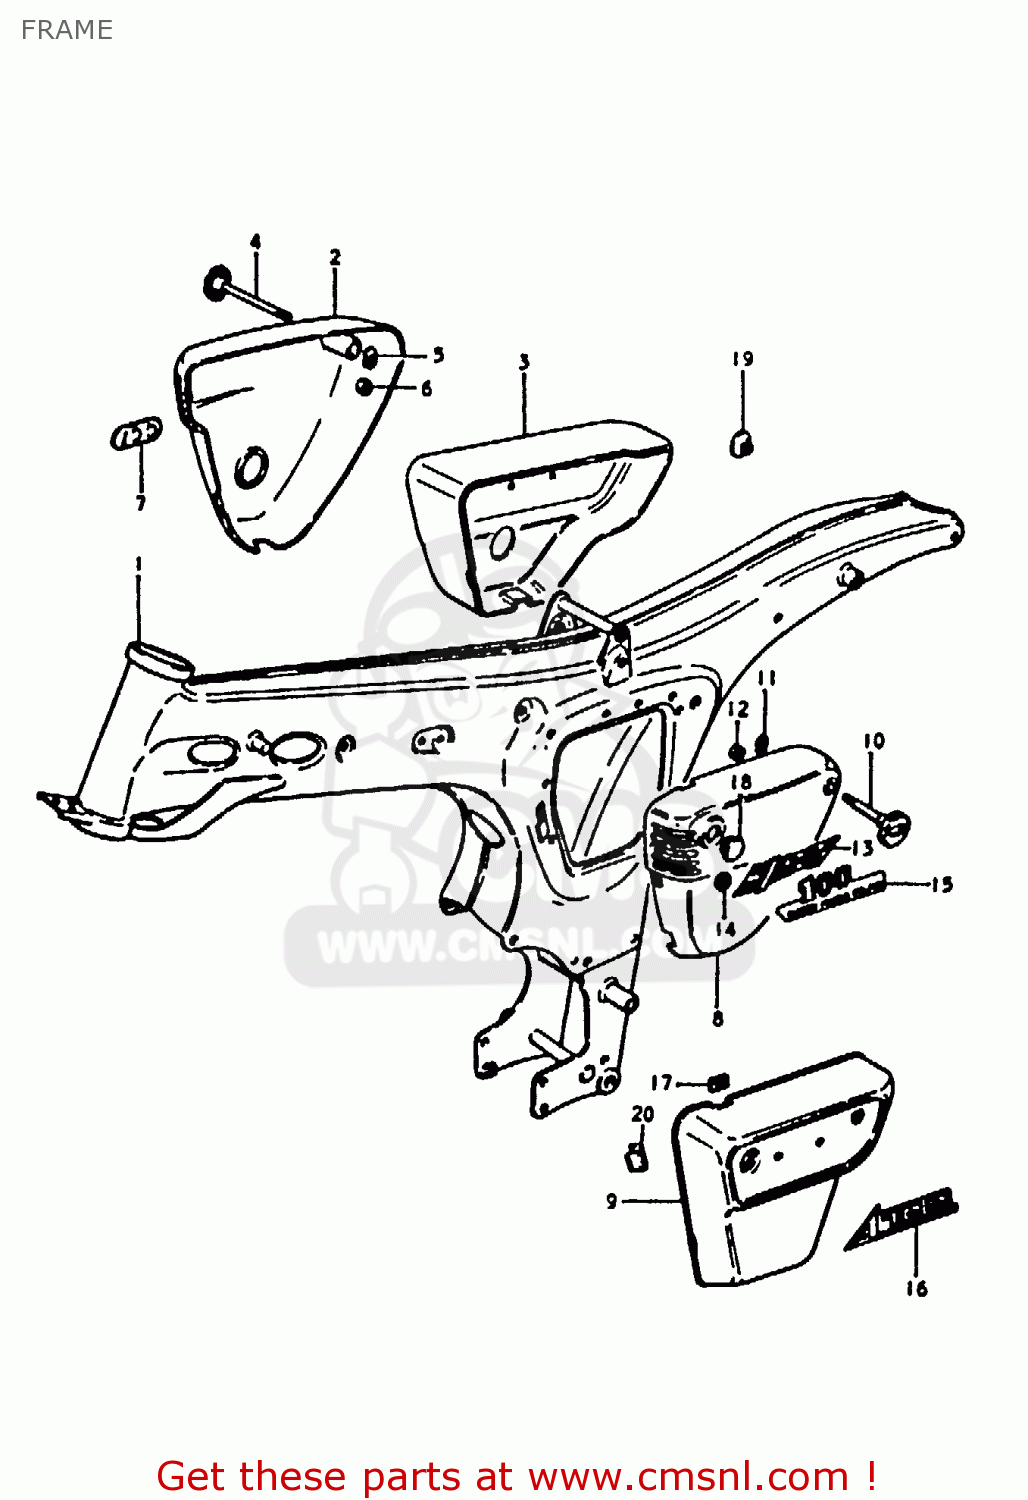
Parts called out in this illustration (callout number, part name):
1	FRAME
2	COVER, FRAME RH
4	KNOB,FRAME COVER,R
5	NUT
7	EMBLEM,CCIS
8	COVER, FRAME LH
10	KNOB,FRAME COVER,L
11	NUT
13	EMBLEM
14	NUT
19	CAP
